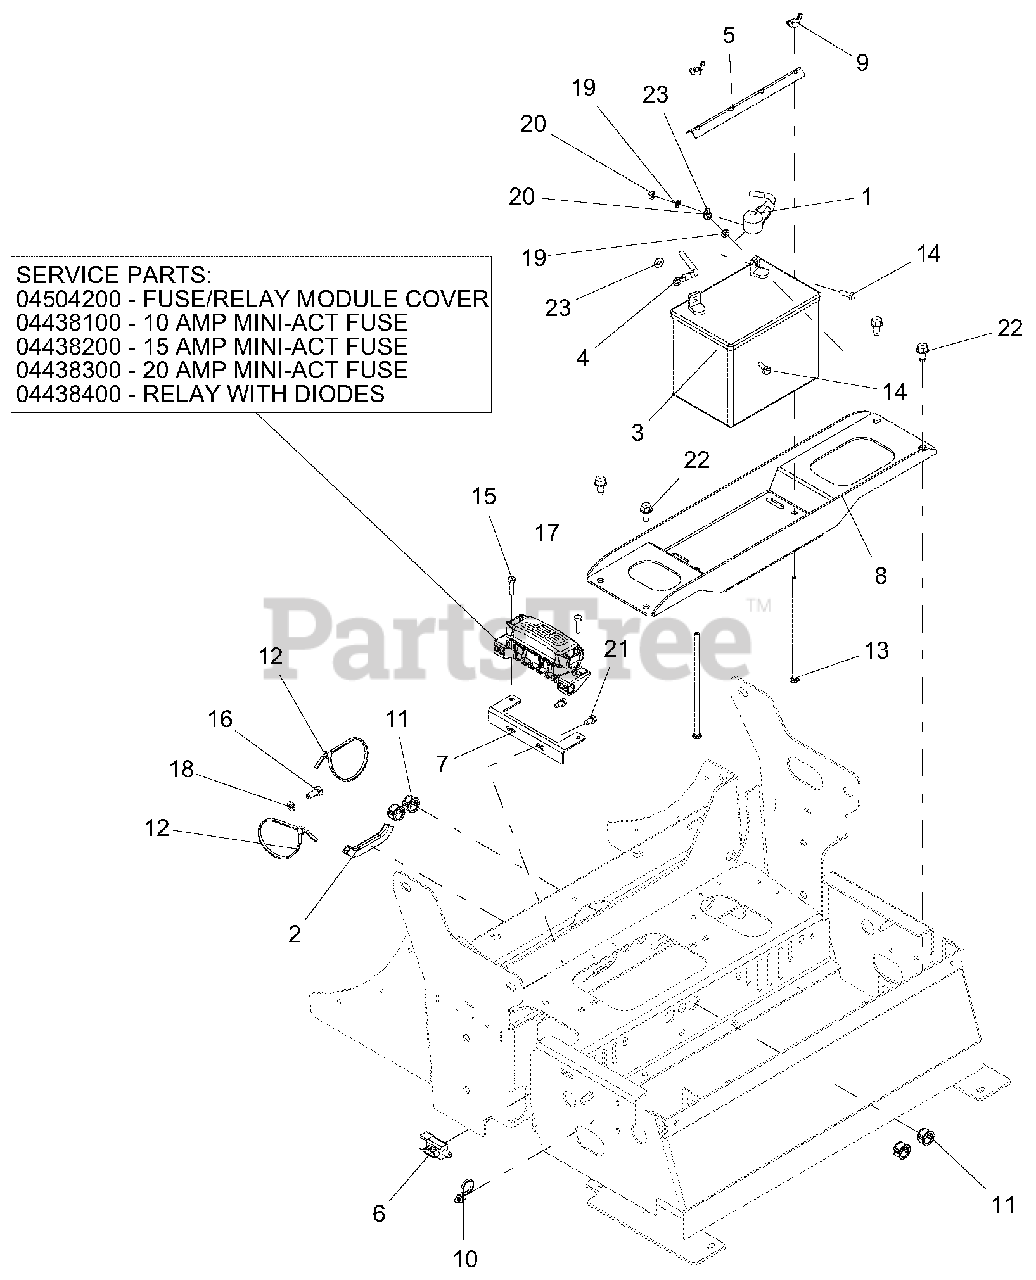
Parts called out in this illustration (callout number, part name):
1	CABLE, POS BATT W/ BOOTS 6 X 35
2	STRIP, COWL - 1.50 LG
3	BATTERY, 300 CCA 10U1L
4	CABLE, NEGATIVE BATTERY 35.00"
5	HOLD DOWN - BLK
6	SWITCH, SNAP IN -N.O./N.O
7	BRKT, FUSE HOLDER MOUNTING-RED
8	TRAY, BATTERY-RED
9	NUT-LOCKING WING 1/4-20
10	CABLE TIE W/ TREE (.25 HOLE)
11	BUSH, PANEL SNAP .687X.875X.56
12	CABLE, TIE 5.50 LG
13	BLT-RDHDSQNK .25-20X7.50 G2 YWZC
14	BLT-HEX .25-20X.75 GR5 YWZC
15	@BLT-HEX M6-1.0X25 YWZC
16	@BLT-HEX M8-1.25X20 YWZC
17	HARNESS, PT400 GAS WIRE
17	FUSE/RELAY MODULE COVER
17	10 AMP MINI-ACT FUSE
17	15 AMP MINI-ACT FUSE
17	20 AMP MINI-ACT FUSE
17	RELAY WITH DIODES
18	WSHR-LK .31X.078 REG YWZC
19	WSHR-LK .25X.062 REG YWZC
20	NUT-HEX .25-20 YWZC
21	SCR-TAP .25-20X.50 HWH TR YWZ
22	SCR-TAP .38-16X.75 HWH TR YWZ
23	WSHR-FL-STL.281X.62X.065 YWZC
